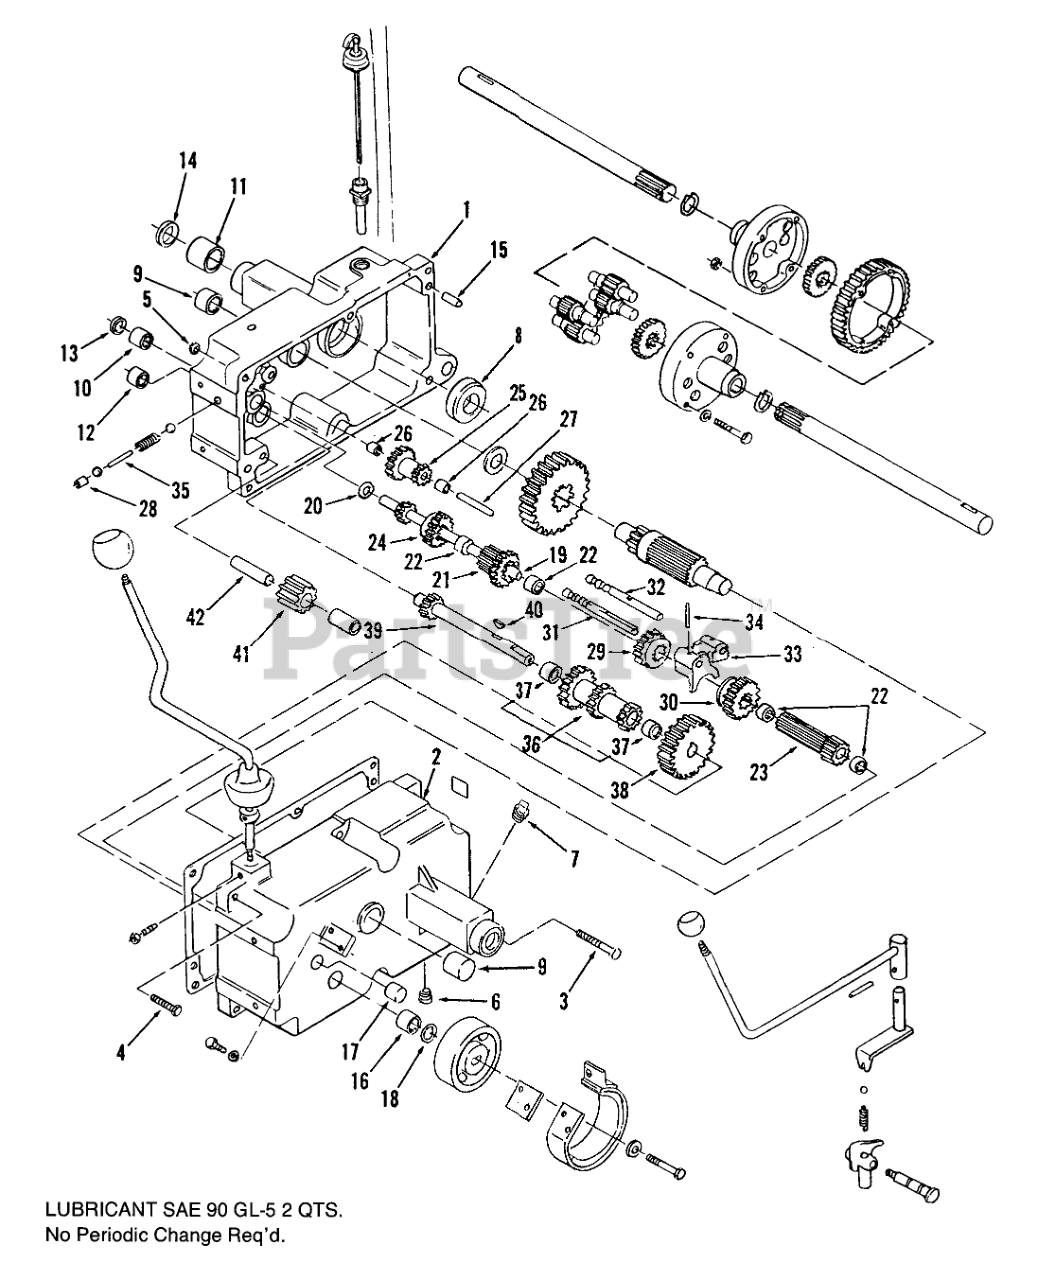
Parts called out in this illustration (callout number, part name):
1	Case Trans RH
2	Case Trans LH
3	Bolt 3/8-16 x 4
4	Bolt
5	NUT
6	PLUG 1/4 PIPE ALLEN
7	Plug
8	BEARING-BALL
9	BEARING-NEEDLE
10	BEARING-NEEDLE
11	BEARING
12	BEARING-NEEDLE
13	SEAL-OIL
14	SEAL-OIL
15	PIN-DOWEL
16	BEARING-NEEDLE
17	Bearing Needle
18	SEAL-OIL
19	SHAFT-INPUT
20	WASHER-THR
21	GEAR
22	BEARING-NEEDLE
23	GEAR
24	GEAR-SLIDING
25	Gear
26	BEARING-NEEDLE
27	GEAR-SHAFT REDUCTION
28	CUP-PLUG
29	GEAR-HI AND 2ND
30	GEAR-LOW AND REVERSE
31	RAIL-SHIFT
32	RAIL-REAR SHIFT
33	FORK-SHIFT
34	PIN-ROLL
35	PIN-SHIFT
